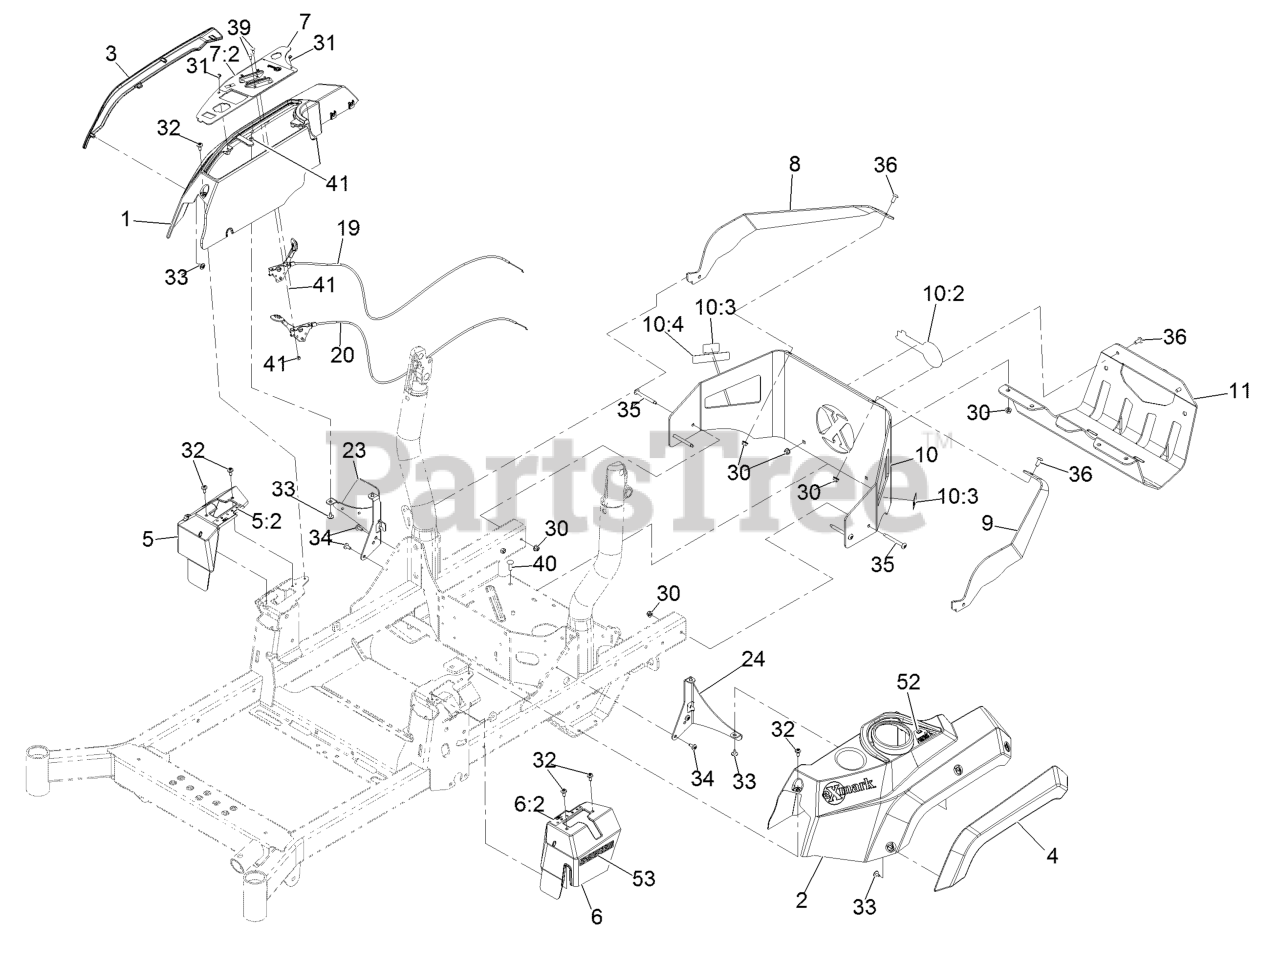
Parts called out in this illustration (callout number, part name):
1	Console-Exmark, RH
2	Console, LH
3	Fender-RH
4	Fender-LH
5	Cover-Control, Motion (RH)
5:2	Decal-Control, Motion (RH)
6	Cover-Control, Motion (LH)
6:2	Decal-Control, Motion (LH)
7	Ctrl Panel ASM W/Decal
7:2	Decal-Control Panel
8	Support-Upper, RH
9	Support-Upper, LH
10	Rear Guard ASM
10:2	Decal-Exmark Logo
10:3	Decal-Warning
10:4	Decal-Arrester, Spark
11	Guard-Muffler
19	Cable-Control, Choke
20	Cable-Control, Throttle
23	Support-Console, RH
24	Bracket-Console, LH
30	Nut-Nyloc 5/16-18 Flg
31	Screw-HWH #10-14 X 1/2
32	Screw-1/4-20 X 1/2 Tf Torx Plus
33	Screw-HWH #10-14 X 1/2 Torx
34	Screw-1/4-20 X .65 Torx Plus
35	Screw-Truss HD 5/16-18 X 2 3/4 Torx Plus
36	Screw-Truss HD 5/16-18 X 3/4 Torx Plus
39	Bolt-Carriage #10-24 X 1/2
40	Bolt-Carriage 5/16-18 X 1 Sp
41	Nut-Nyloc #10-24
52	Decal-Fill, Fuel
53	Decal-S-Series
